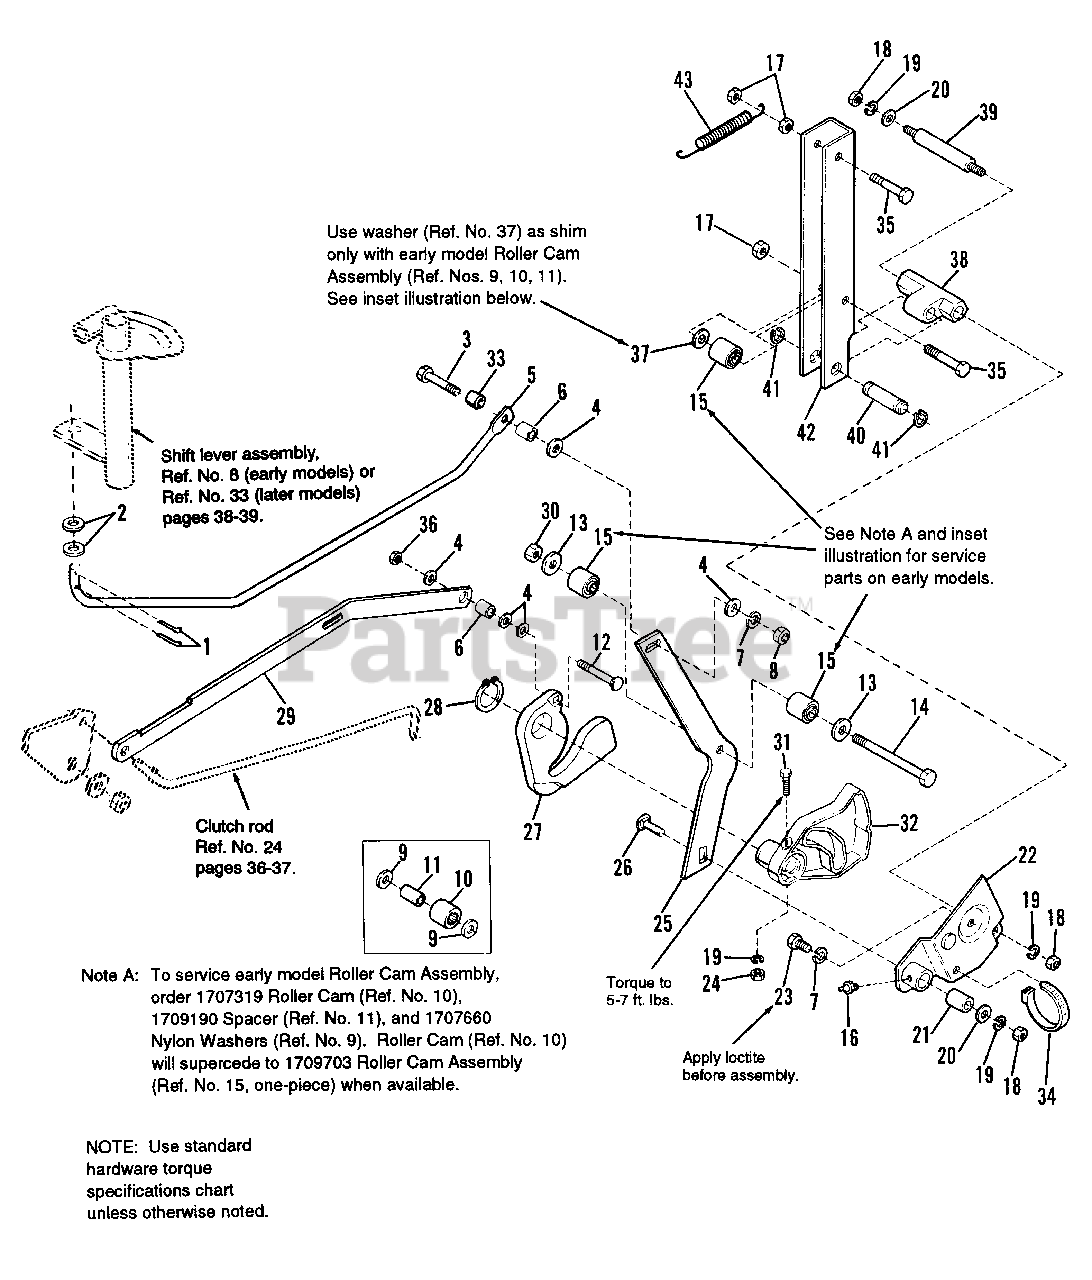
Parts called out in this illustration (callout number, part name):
1	PIN, Cotter
2	WASHER, Plain
3	CAPSCREW, Hex Head 5/16-18 x 2 G5
4	WASHER, Flat
7	LOCKWASHER, 5/16
8	NUT, Hex, 5/16-18
9	WASHER, Nylon
10	ROLLER, Cam
11	SPACER, Cam, Control
12	CARRIAGE BOLT, 5/16-18 x 1-3/4
13	WASHER, Flat
14	CAPSCREW, Hex, 1/4-20 x 2-1/4
15	ROLLER, Cam
16	FITTING, Lube 1/4
17	NUT, Hex, Center Lock, 1/4-20
18	NUT, Hex, 1/4-20
19	LOCKWASHER, 1/4
20	WASHER, Flat, 1/4
22	BRACKET, Control Support
23	CAPSCREW, Hex, 8 mm-1.25 x 19 mm
24	NUT, Hex, 6 mm-1.0
25	LEVER, Speed Control
26	CARRIAGE BOLT, 1/4-20 x 2
27	CAM, Neutral Return
28	RING, Retaining
29	ROD, Return-To-Neutral
30	NUT, Hex, Lock ESNA 1/4-20
31	CAPSCREW, Hex, 6mm-1.0 x 55 mm
32	CAM, Control-Directional
33	SPACER, 5/16 x 1/8 O.D. x 3/4 Long
34	TIE, Self-Locking
35	CAPSCREW, Hex, 1/4-20 x 1-1/2
36	NUT, Hex Lock ESNA 5/16-18
37	WASHER
38	LEVER, Neutral Adj.
39	PIVOT, Adj. Lever
41	RING, Retaining, Ext. 3/8
42	ARM, Neutral Roller
43	SPRING, Extension
